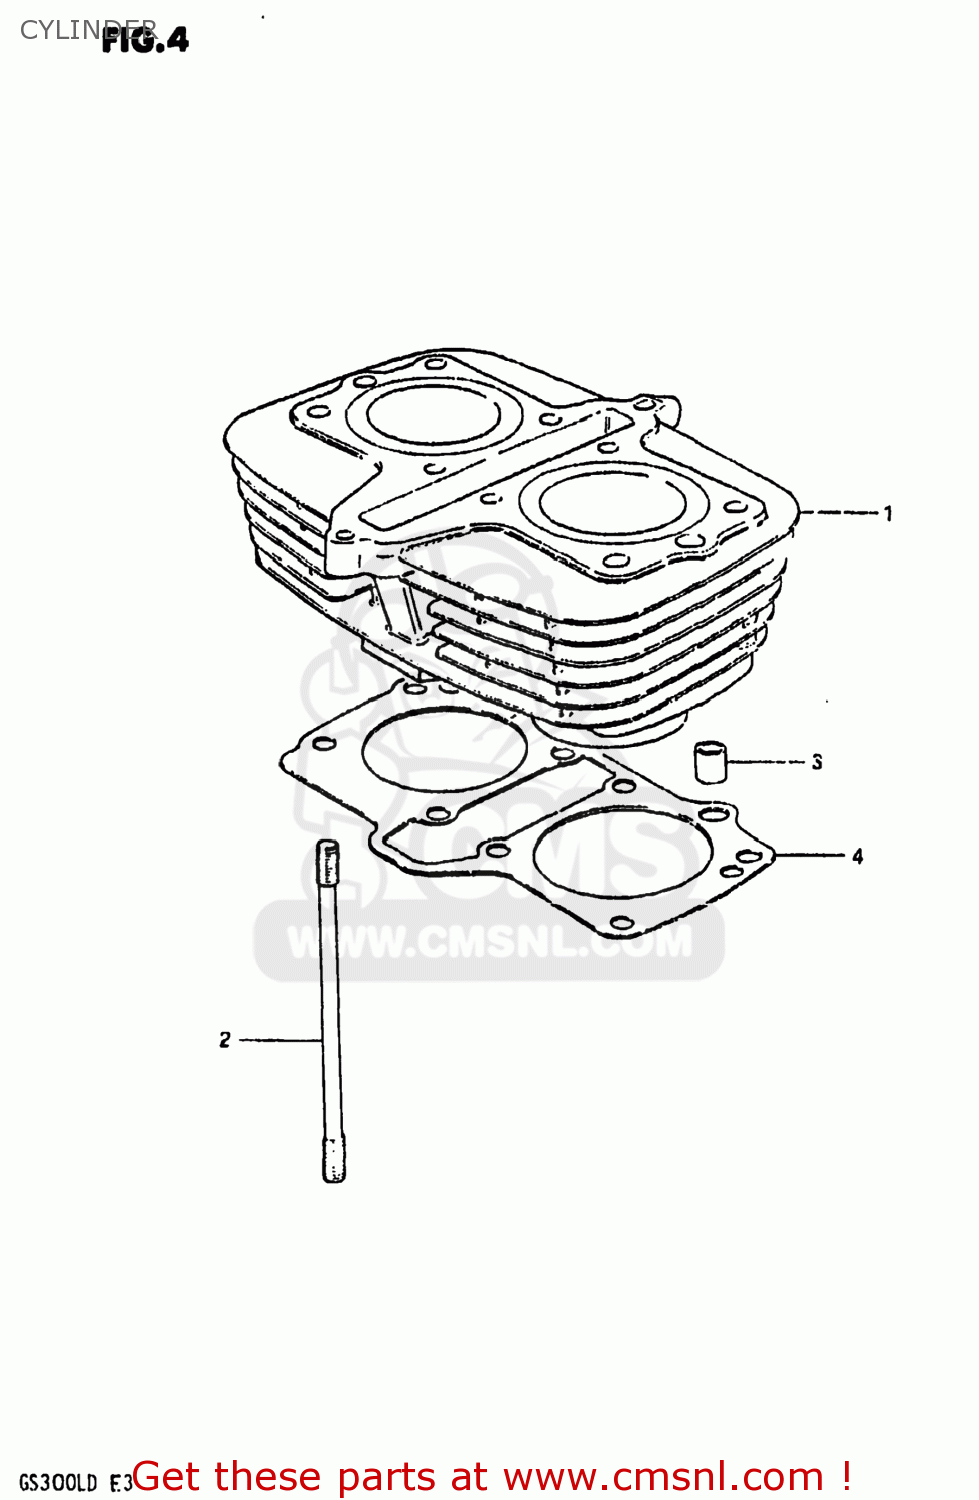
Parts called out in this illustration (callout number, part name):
1	CYLINDER
2	STUD
3	PIN
4	GASKET,CYLINDER
